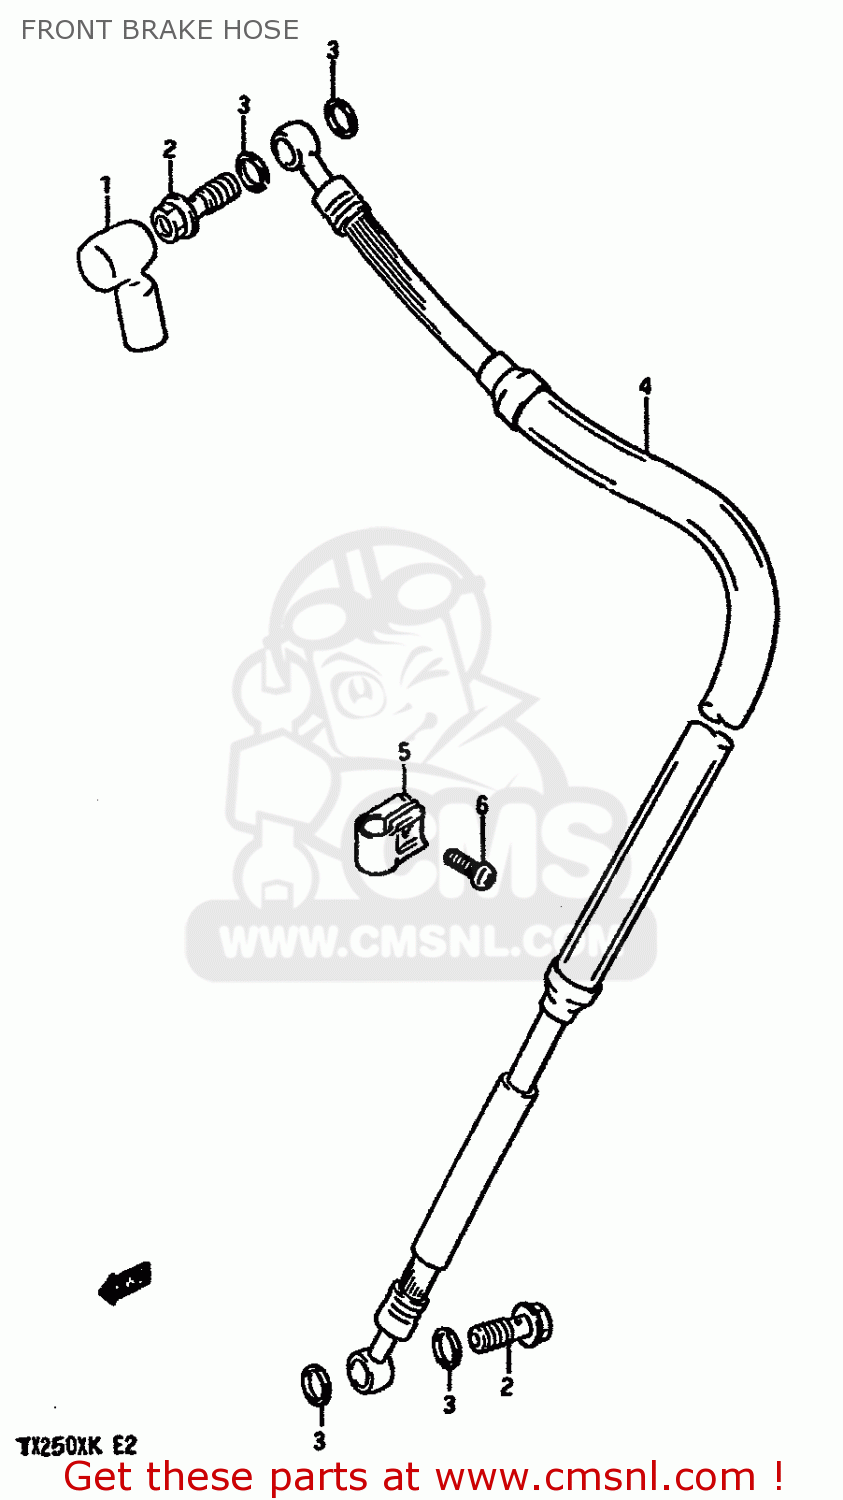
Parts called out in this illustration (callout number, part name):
1	BOOT,MASTER CYLINDER
2	BOLT UNION
3	WASHER(10X15X1.5)
4	HOSE,FRONT BRAKE
5	CLAMP,BRAKE HOSE
6	SCREW
